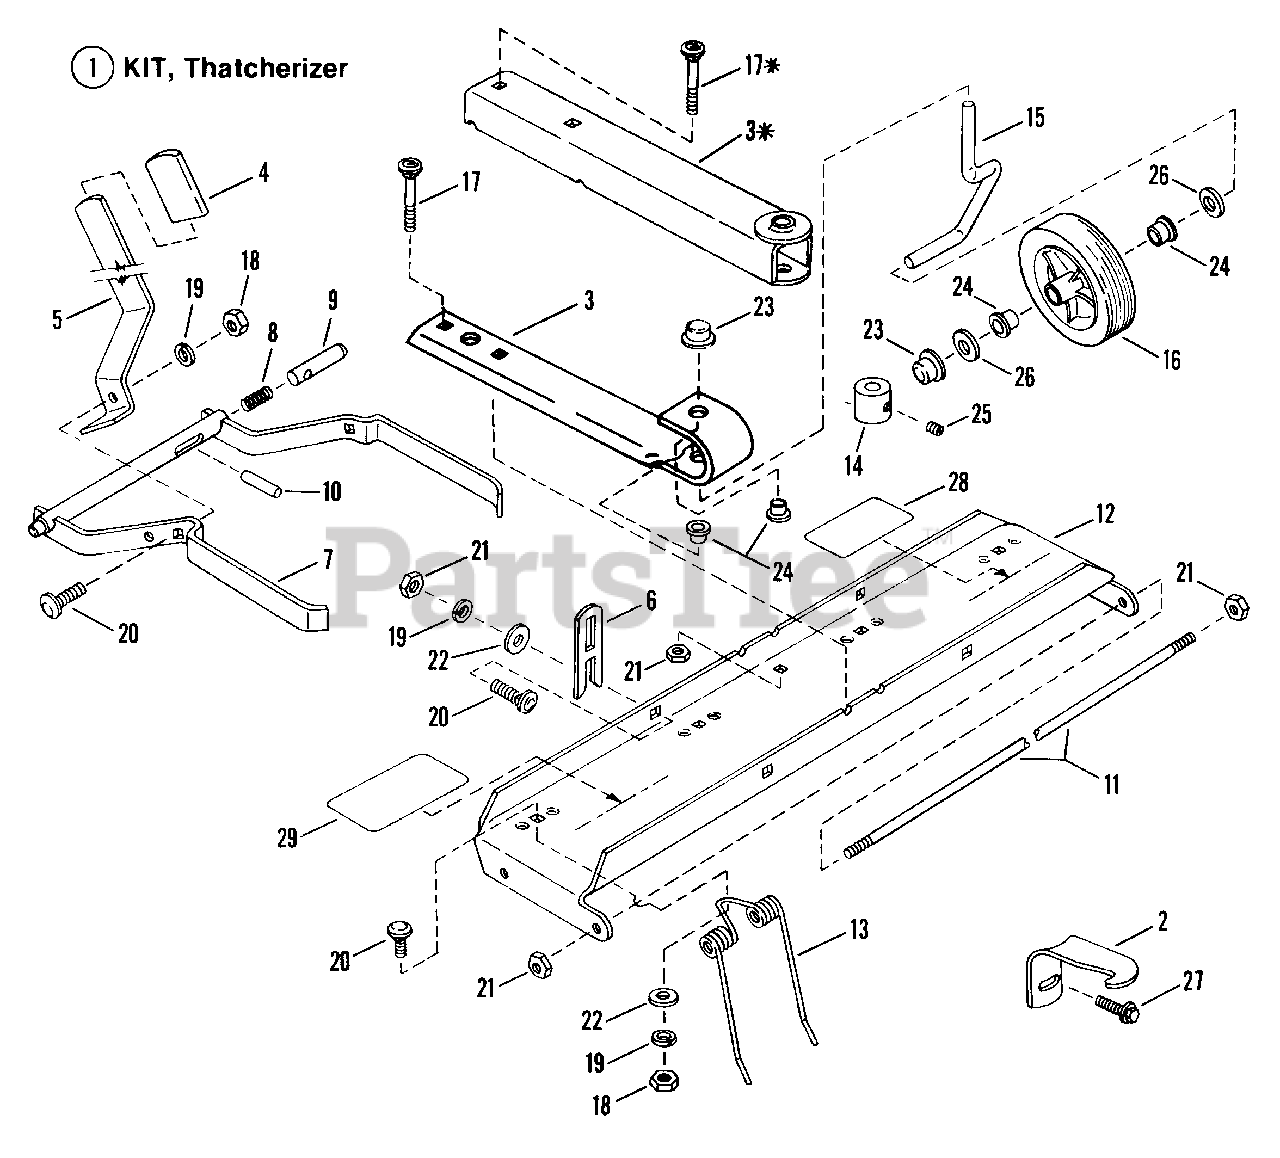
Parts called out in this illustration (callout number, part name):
1	KIT, Thatcherizer
2	BRACKET, Transport Lock
3	SUPPORT, Wheel Assembly
4	GRIP, Handle
5	HANDLE, Lift
6	STRAP, Frame Mount
7	FRAME, Thatcherizer
8	SPRING, Compression
9	PIN, Locking
10	ROLL-PIN
11	ROD, Tine Retainer
12	TRAY,Tine (28")
13	SPRING, Tine Thatching
14	BUSHING
15	AXLE,Wheel
16	WHEEL, 7"
17	CARRIAGE BOLT, 1/4-20x1 3/4"
18	NUT, 5/16-18 Hex
19	LOCKWASHER, 5/16 Split
20	CARRIAGE BOLT, 5/16-18x1"
21	LOCKNUT, 1/4-20 Hex
22	WASHER, Reinforcing
23	PUSH-NUT, 1/2"
24	BEARING, Nyliner, Snap-In
25	SET-SCREW, 5/16-18x1/4" Slotted
26	WASHER, 1/2" SAE
27	SCREW, 5/16-18x3/4" HHS-Tapping
28	DECAL, Instruction
29	DECAL, Thatcherizer
